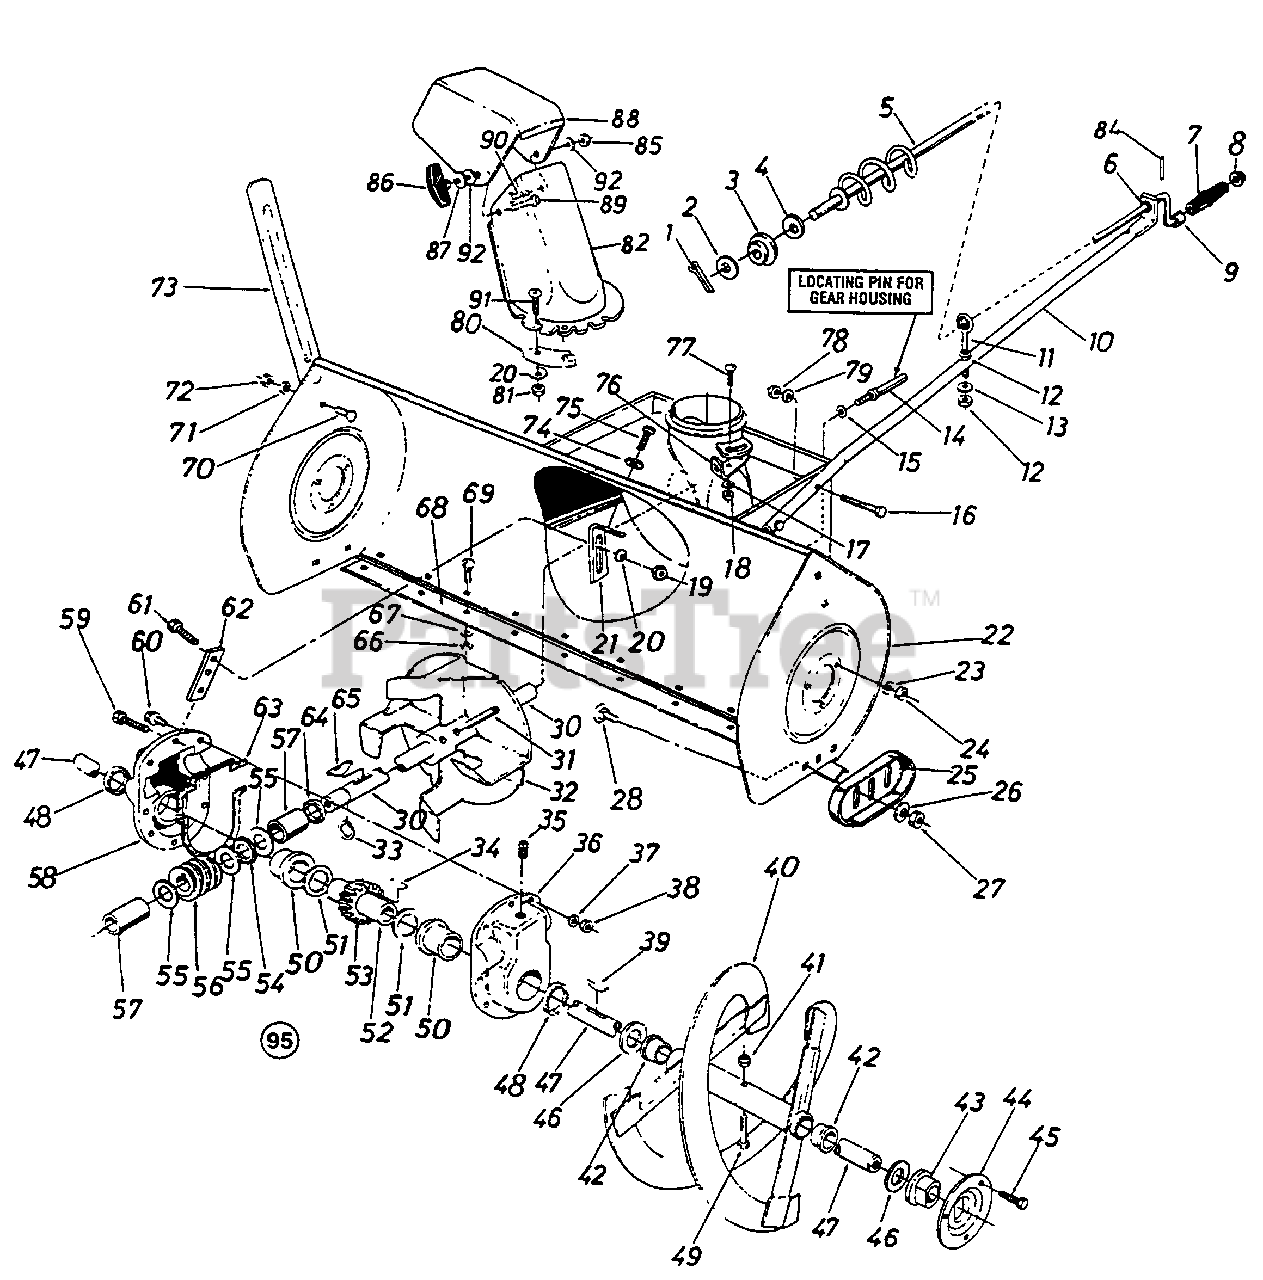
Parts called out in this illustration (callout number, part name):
1	Cotter Pin
2	Fl-Wash .39 I.D. x .62" O.D.
3	Plastic Bushing
4	Fl-Wash .385" I.D. x .62" O.D.
5	Chute Crank Ass'y.
6	Plastic Bushing
7	Knob (Black)
8	Push Nut 3/8" Rod
9	Spacer.385 l.D. x .50" O.D.
12	Hex Nut 5/16-18 Thd.
13	Bell-Wash .345" l.D. x .88" O.D.
14	Stud 3/8-16 x 2.75" Lg.
15	Bell-Wash .40" I.D. x .88" O.D.
16	Hex Bolt 3/8-24 x 1.25" Lg.
17	Bell-Wash .345" i.D. x .88" O.D.
18	Hex Nut 5/16-18 Thd.
19	Hex Nut 1/4-28 Thd.
20	Bell-Wash .265" I.D. x .75" O.D.
22	45" Snow Thrower Housing Ass'y.
23	L-Wash. 5/16" I.D.
24	Hex Nut 5/16-18 Thd.
26	Bell-Wash .40" I.D. x .88" O.D.
27	Hex Jam Nut 3/8-16 Thd.
28	Carriage Bolt 3/8-16 x .62" Lg.
30	Blower Axle .875" Dia. x 14.75" Lg.
31	Spring Pin Spir. 5/16" Dia. x 1.75" Lg.
34	#91 Woodr-Key 1/4 x 3/4" Dia. (HDN)
35	Vent Plug
36	Comp. Gear Hsg. Half - L.H.
37	Spr-Wash .32" I.D. x .62" O.D.
38	Hex Ins. L-Nut 5/16-18 Thd.
39	#91 Woodr-Key 1/4 x 3/4" Dia. (HDN)
41	Hex ins. L-Nut 5/16-18 Thd.
42	Plastic Bushing
43	Flange Brg. w/Flats 1" I.D.
44	Bearing Housing
45	Hex Sems Bolt 5/16-18 x .75" Lg.
46	Fl-Wash. 1.0" I.D. x 1.75" O.D.
47	Spiral Axle
48	Flange Bearing 1.503" I.D.
49	Shear Bolt 5/16-18 x 1.75" Lg.
50	Oil Seal 1.50" I.D.
51	Fl-Wash. 1.50" I.D. x 2.0" O.D.
52	Worm Gear Shaft
53	Double Threaded Worm Gear - L H.
54	Thrust Brg .88" I.D. x 1.44" O.D.
55	Fl-Wash .88" I.D. x 1.4" O.D.
56	Double Threaded Worm - L.H.
57	Sleeve
58	Complete Gear Hsg. Half - R.H.
59	Hex Bolt 5/16-18 x 1.25" Lg.
60	Hex Bolt 5/16-18 x 1.0" Lg. (Gr. 5)
61	Hex Bolt 1/4-28 x .75" Lg.
62	Gear Housing Support Plate
63	Rubber Gasket
64	Oil Seal -.875" I.D.
65	#9 Hi-Pro Key 3/16 x 3/4" Dia. (HT)
66	Hex Nut 5/16-18 Thd.
67	L-Wash. 5/16" I.D.
69	Carriage Bolt 5/16-18 x 1.0" Lg.
70	Carriage Bolt 5/16-18 x .62" Lg.
71	L-Wash. 5/16" I.D.
72	Hex Nut 5/16-18 Thd.
73	Guide Blade
74	Bell-Wash .345 1.D. x .88" O.D.
75	Hex Wash. Hd. AB-Tap Scr. 5/16 x .75" Lg.
77	Carriage Bolt 5/16-18 x .75" Lg.
78	Hex Ins. L-Nut 3/8-24 Thd.
79	L-Wash. 3/8" I.D.
80	Chute Flange Keeper
81	Hex Nut 1/4-20 Thd.
82	Lower Chute Ass'y.
84	Bell-Wash .345" I.D. x .88" O.D.
85	Hex Cent. L-Nut 5/16-18 Thd.
86	Knob Handle
87	Bell-Wash .345" I.D. x .88" O.D.
88	Upper Chute Ass'y.
89	Carriage Bolt 5/16-18 x 1.0" Lg.
90	Carriage Bolt 5/26-18 x .62" Lg.
91	Truss Mach. Scr. 1/4-20 x .75"
92	Roll Pin .12" Dia. x .63"
95	Worm Gear Box Ass'y. Comp.
